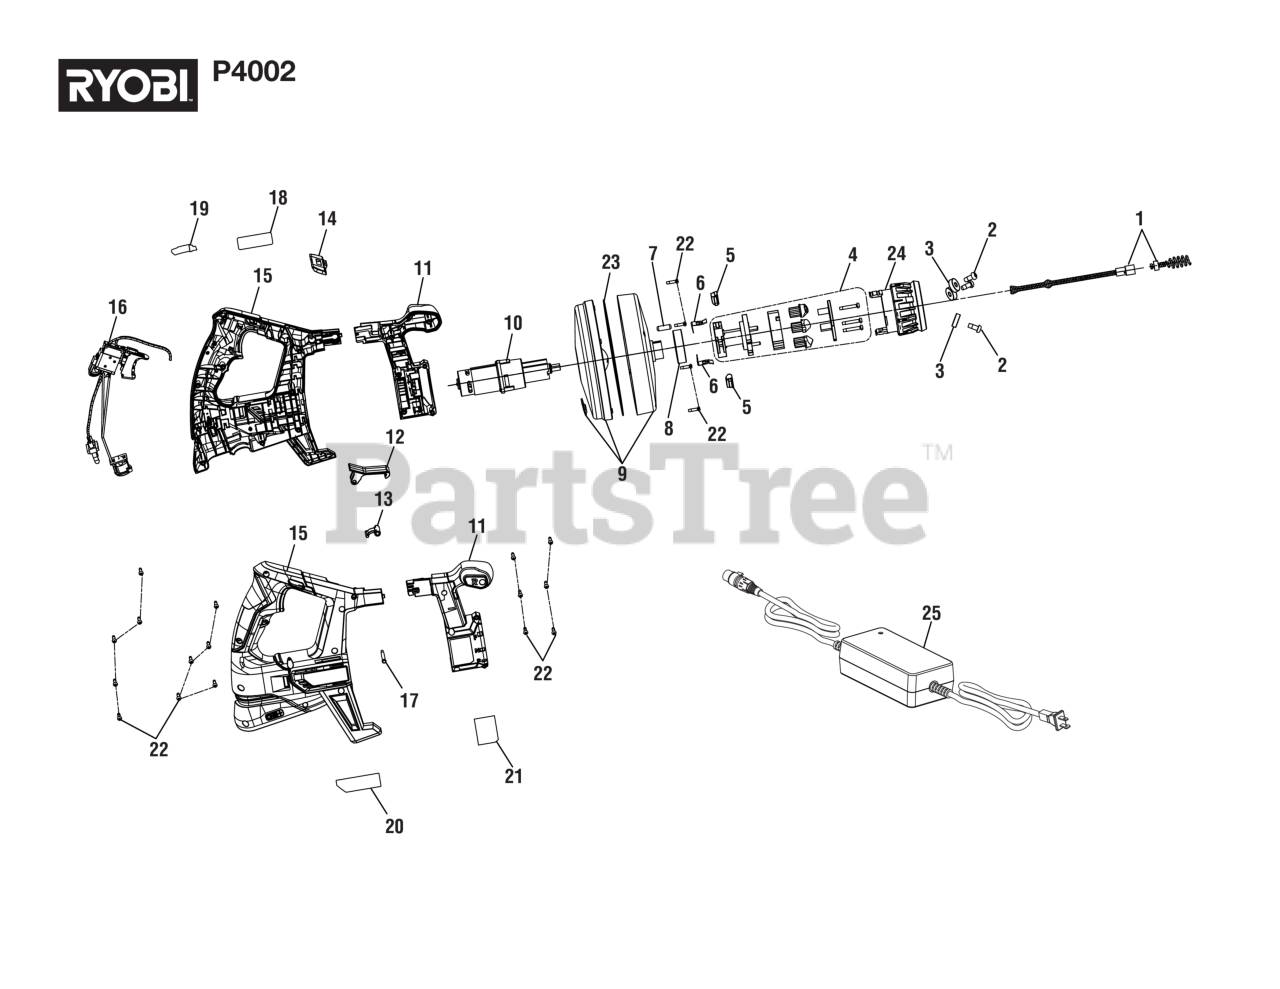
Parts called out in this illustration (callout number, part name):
1	Snake Cable (Auger) w/Removable Tip
2	Screw (M6 x 14 mm)
3	Ball Bearing (6262RS)
4	Direction Control Assembly
5	Slide Block
6	Lock Spring Plate
7	Rubber Bumper
8	Ball Bearing (6005 2Z)
9	Drum Assembly
10	Motor and Gear Train Assembly
11	Front Handle Assembly
14	Forward/Reverse Button
15	Housing Assembly
16	Variable Speed Switch Assembly
17	Screw (M3 x 33 mm, T15 Torx Pan Hd.)
18	Logo Label
19	Lithium Label
20	Data Label
21	Warning Label
22	Screw (M3.5 x 14 mm, T10 Tox Pan Hd.)
24	Feed Direction Selector Collar
25	Power Supply Cord
